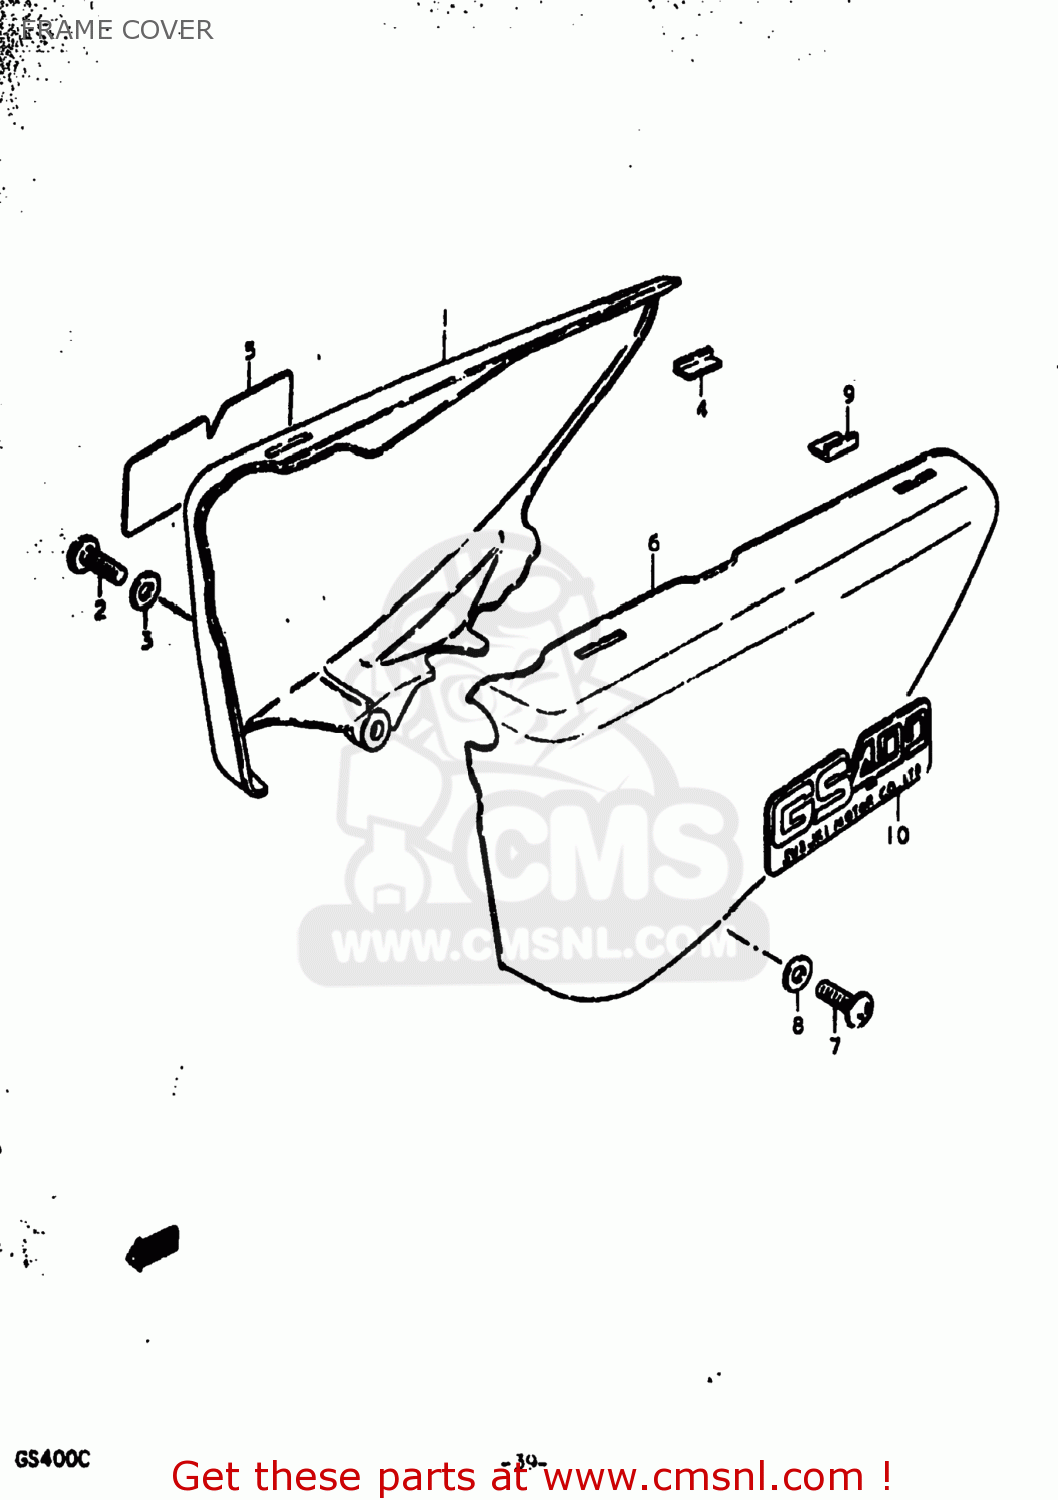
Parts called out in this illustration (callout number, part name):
1	COVER,FRAME,RIGHT
2	SCREW (6X15)
3	WASHER (6.5X18X1.6)
4	CUSHION,FRAME COVER
5	EMBLEM,FRAME COVER
6	COVER,FRAME,LEFT
7	SCREW
8	WASHER (6.5X18X1.6)
9	CUSHION,FRAME COVER
10	EMBLEM,FRAME COVER
